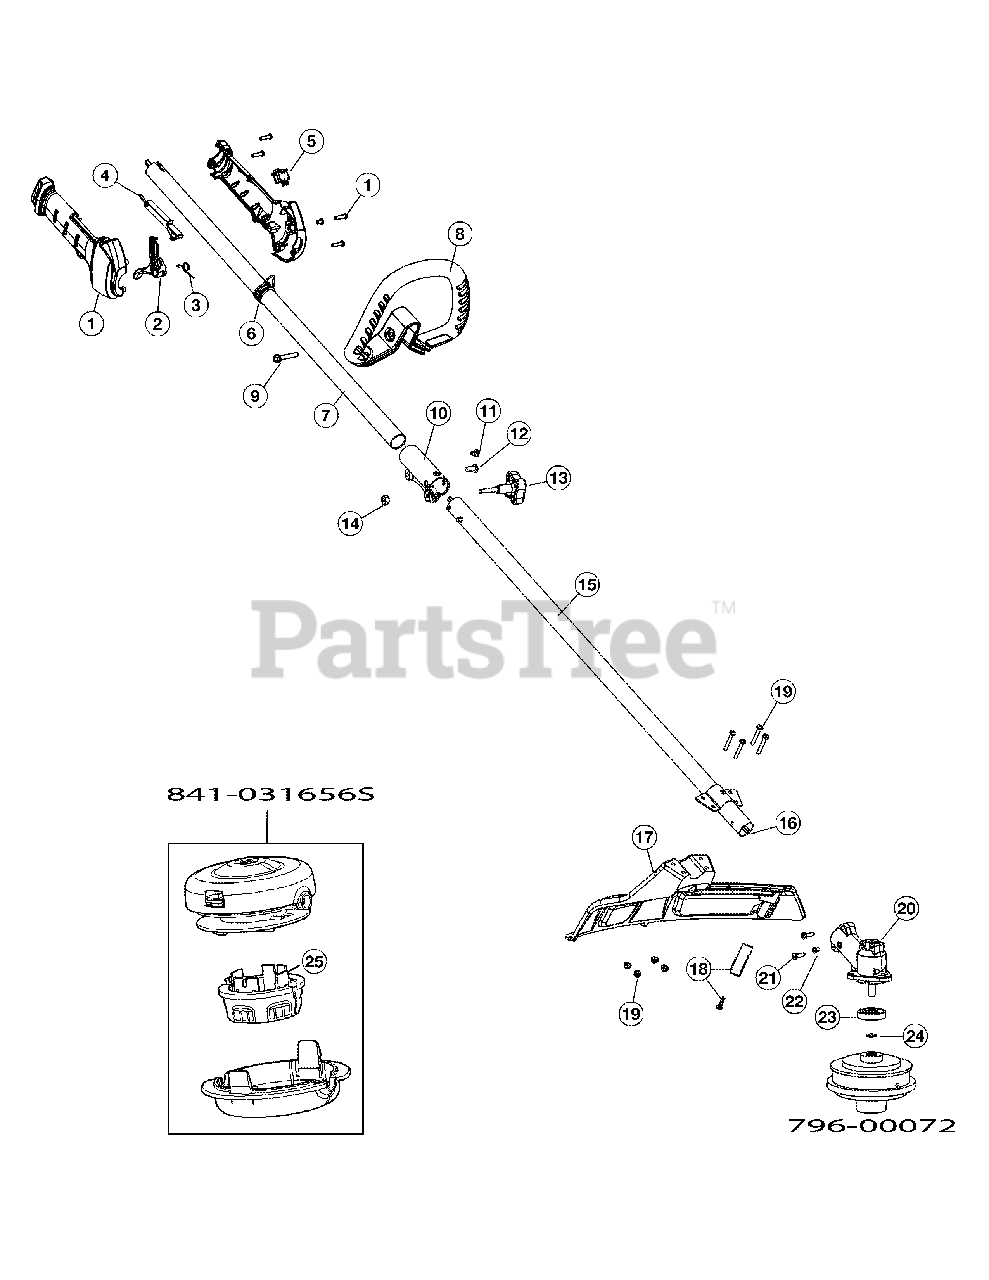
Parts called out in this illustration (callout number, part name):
1	Throttle Housing Assembly
2	Throttle Trigger
4	Throttle Lock-out
6	Shoulder Strap Clip
7	Upper Drive Shaft Housing Assembly
8	D-Handle Assembly
10	Split Boom Coupler
11	Coupler Anti-Rotation Screw
13	Adjustment Knob
14	Knob Retaining Nut
15	Lower Drive Shaft Housing Assembly
16	Lower Flexible Drive Shaft
17	Shield Assembly
18	Blade Assembly
19	Shield Mounting Screw & Nut
21	Gearbox Mounting Hardware
22	Anti-Rotation Screw
23	Blade Driver
796-00072	Cutting Head Assembly
841-031656S	Cutting Head Assembly
